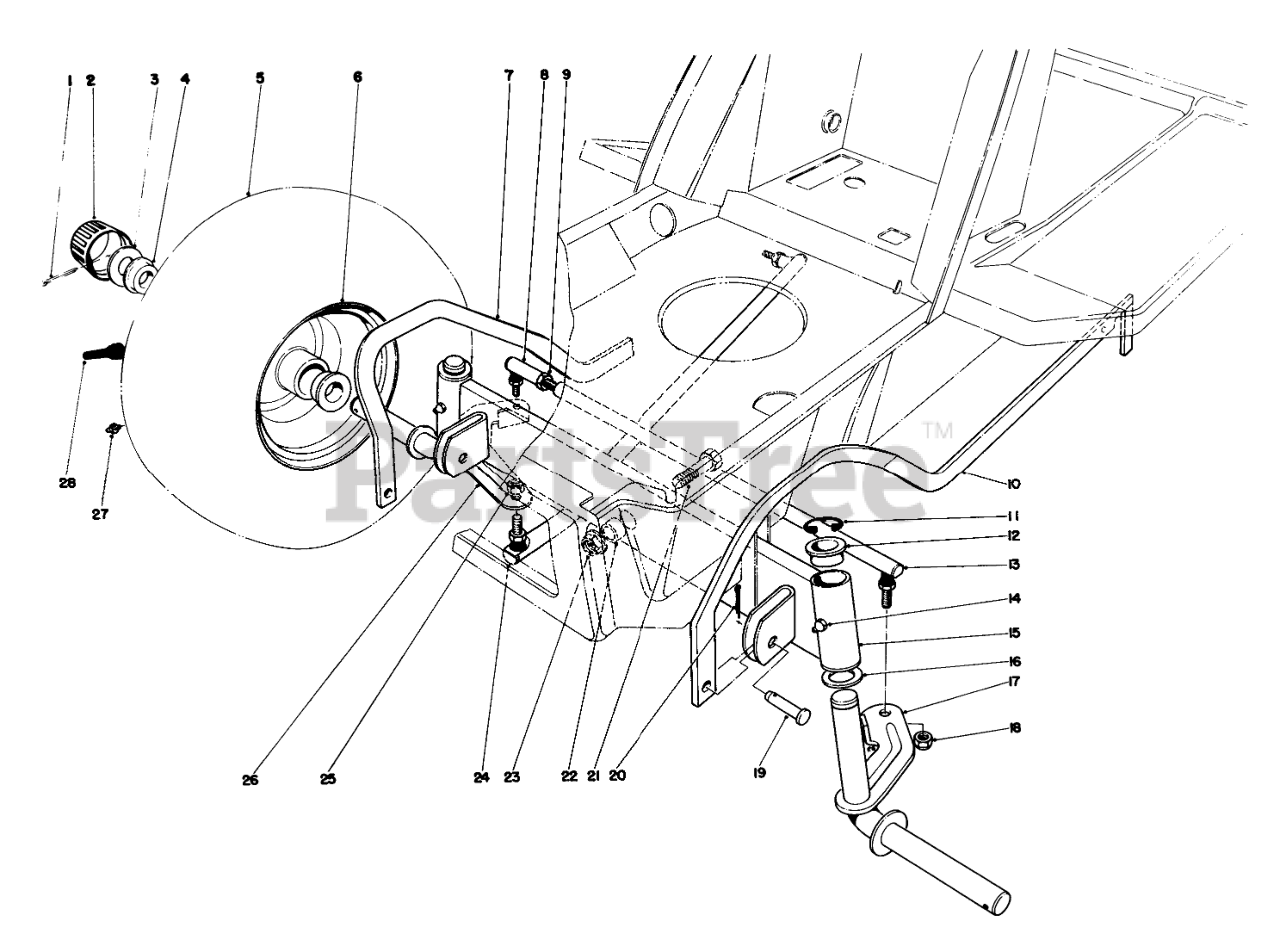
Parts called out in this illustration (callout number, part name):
1	PIN-COTTER
2	Cap-Hub
3	WASHER-PLAIN
4	Bearing
5	TIRE-FRONT
6	FRONT WHEEL
7	RH DECK PARALLEL LINK R
8	JOINT-BALL
9	NUT-JAM
10	LH DECK PARALEL LNKR
11	E-RING
12	BEARING-FLANGE
13	Tie Rod Steering (Incl.Ref.#8 & 9)
14	GREASE FITTING
15	Front Axle (Incl. Ref. #12)
16	WASHER-THRUST
17	Spindle L.H.
18	NUT-LOCK, NI
19	PIN-CLEVIS
20	PIN-COTTER
21	SCREW-HH
22	SPACER-AXLE, FRONT
23	NUT-HF
24	STEERING ARM B
25	NUT-HEX
26	SPINDLE WA RH B
27	FITTING-GREASE
28	STEM-VALVE
